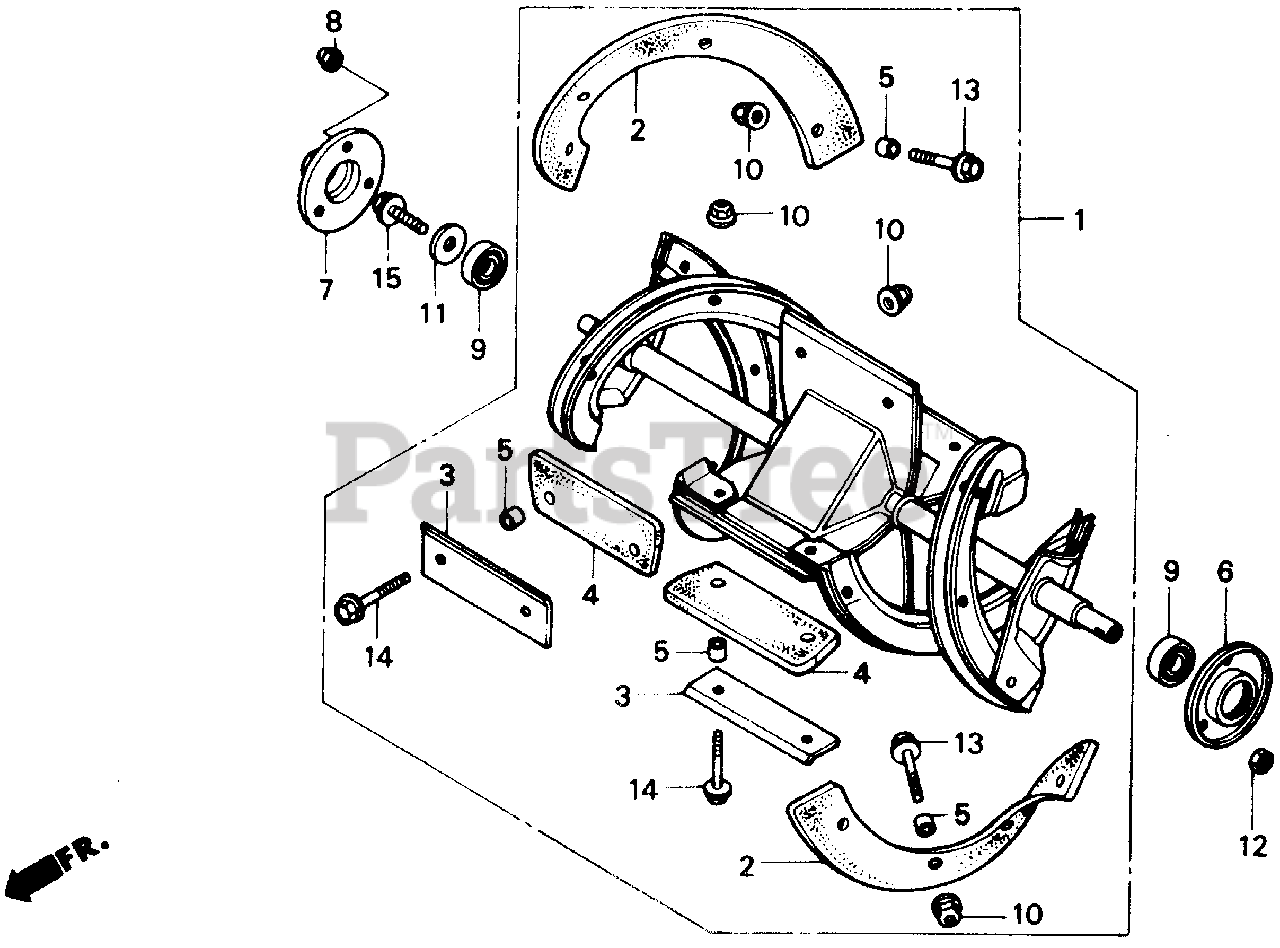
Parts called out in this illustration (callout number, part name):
1	AUGER ASSY.
2	RUBBER, AUGER
3	HOLDER, RUBBER
4	RUBBER, BLOWER
5	COLLAR, AUGER RUBBER
6	HOLDER, L. AUGER
7	HOLDER, R. AUGER
8	NUT, CAP (6MM)
9	BEARING, RADIAL BALL (6203)
10	NUT, SELF-LOCK (6MM)
11	WASHER (8MM)
12	NUT, HEX. (6MM)
13	BOLT, FLANGE (6X20)
14	BOLT, FLANGE (6X25)
15	BOLT, FLANGE (8X16)
